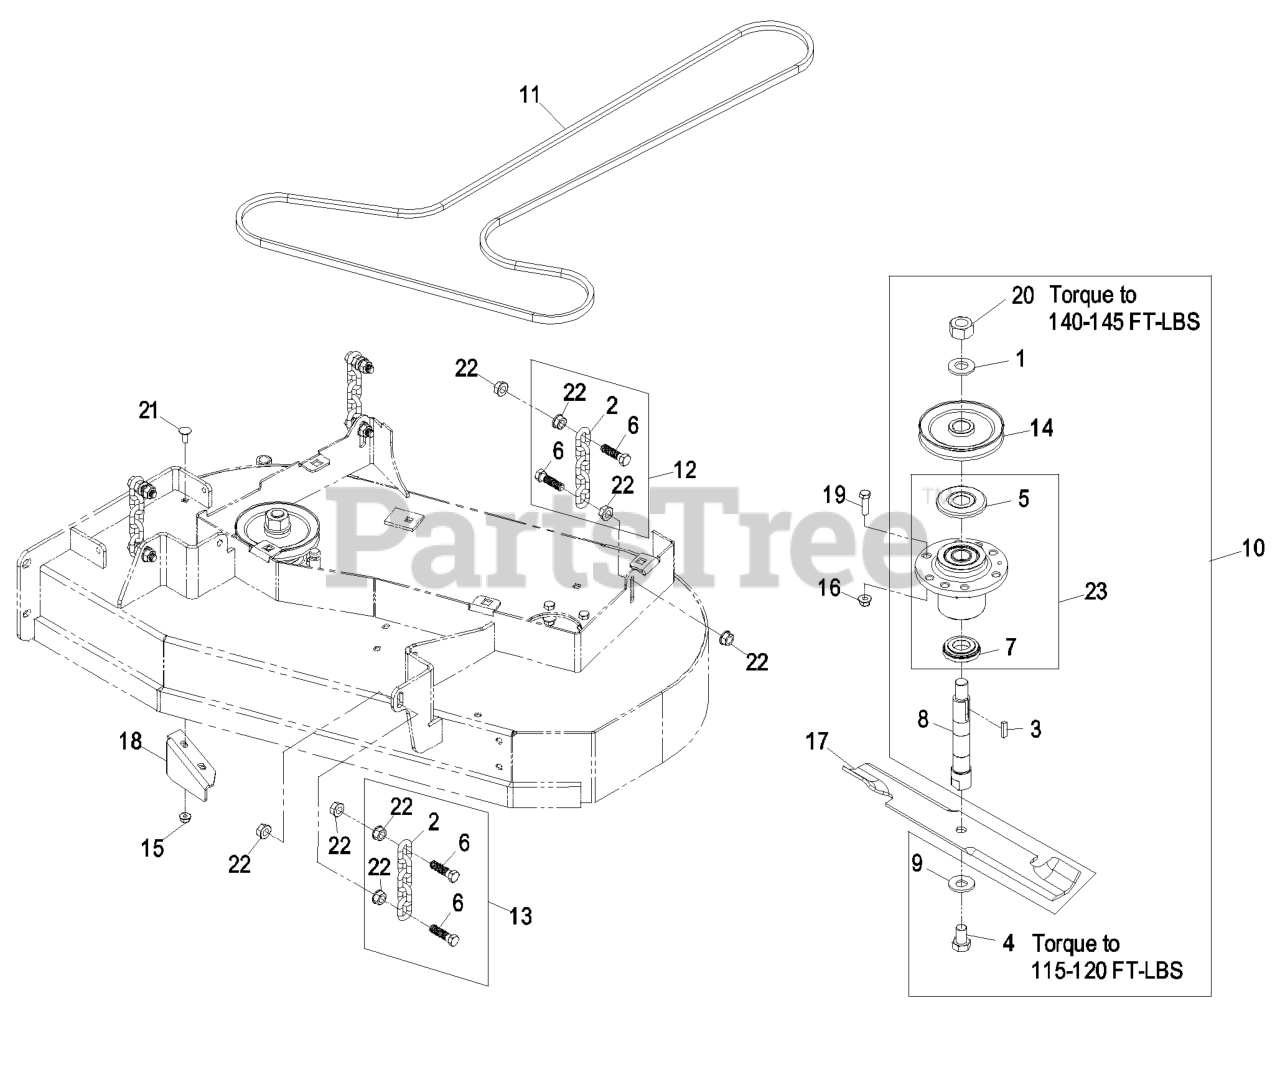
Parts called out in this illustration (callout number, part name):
1	WASHER-SPRING
2	CHAIN-LIFT, DECK
3	KEY-RECTANGLE
4	SCREW-CAP
5	GUARD-BEARING, TOP
6	SCREW-HH
7	SPACER-GUARD, BOTTOM
8	SPINDLE,SHAFT
10	ASM,CUTTER HOUSING COMPLE
11	BELT,A107.40
12	DECK CHAIN ASM
13	DECK CHAIN ASM
14	PULLEY,SPINDLE
15	NUT-HF, NI
16	NUT-HF, NI
18	BAFFLE,DISCHARGE
19	SCREW-HH
20	NUT-HH
21	SCREW-CARR
23	KIT, CUTTER HOUSING
